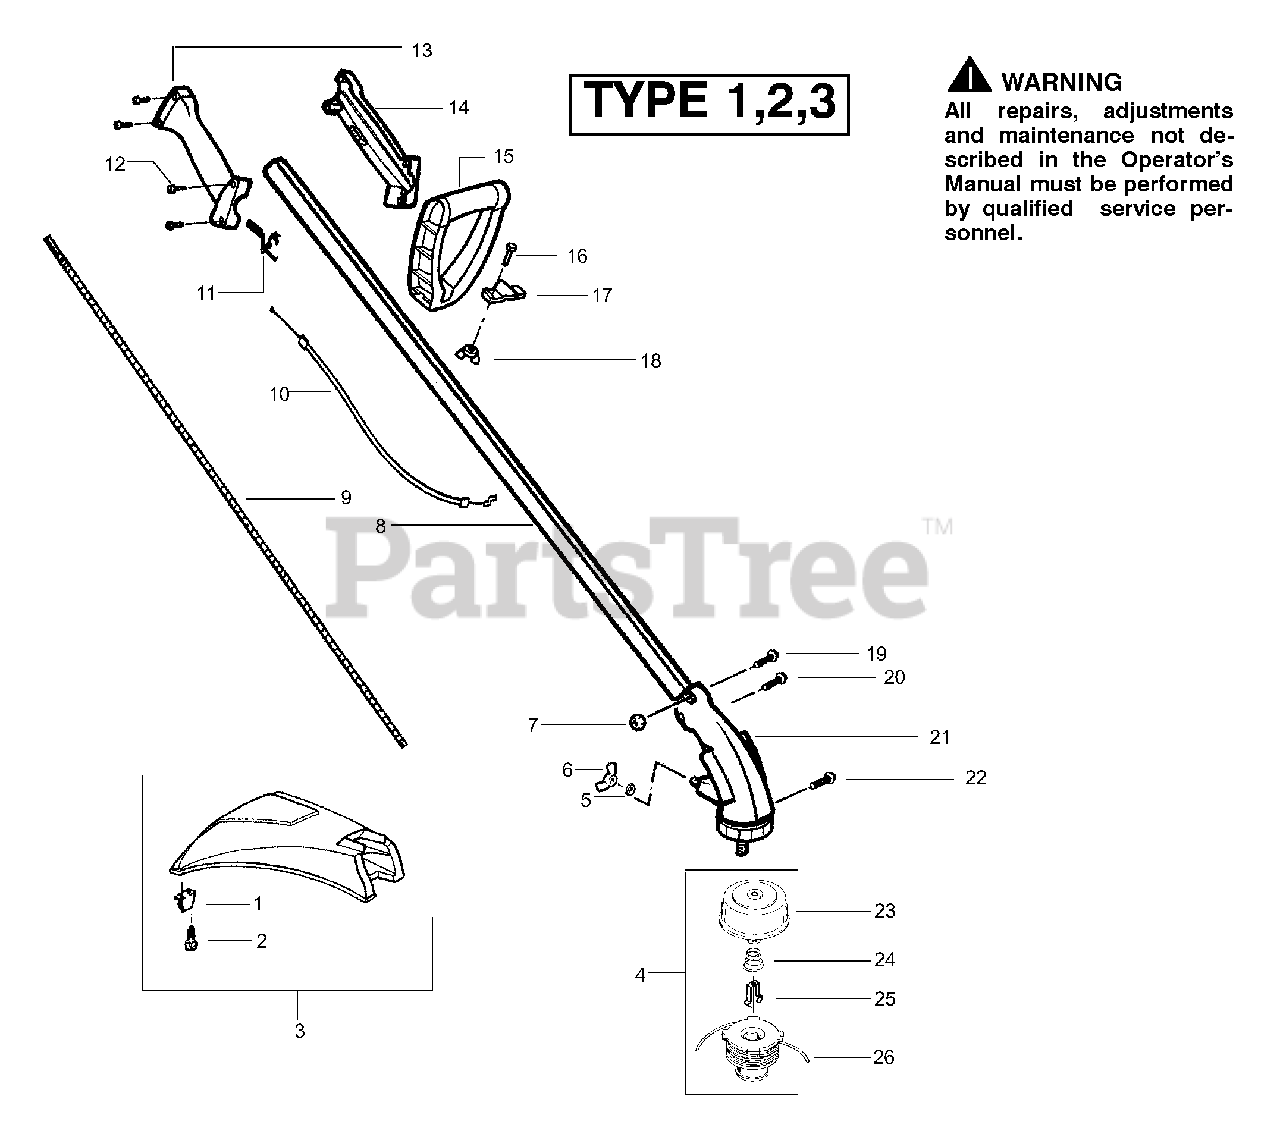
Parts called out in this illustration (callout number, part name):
1	Line Limiter
2	Screw-Line Limiter
3	Shield Kit Ass'y.
4	Accy-TNG 6 Head 5/16 rh 2x
6	Wingnut-Gear Box
7	Locknut-Gear Box
8	Drive Shaft Hsg. Ass'y
9	Flex-Drive Shaft
10	Throttle Cable Ass'y.
12	Screw-Throttle Hsg.
13	Throttle Hsg. (Right)
14	Throttle Hsg. (Left)
15	Assist Handle
16	Bolt-Handle
17	Clamp-Handle
18	Wingnut-Handle
21	Kit-Gear Box
23	Kit-Hub Ass'y
25	Retainer
26	Accy-Spool w/Line
